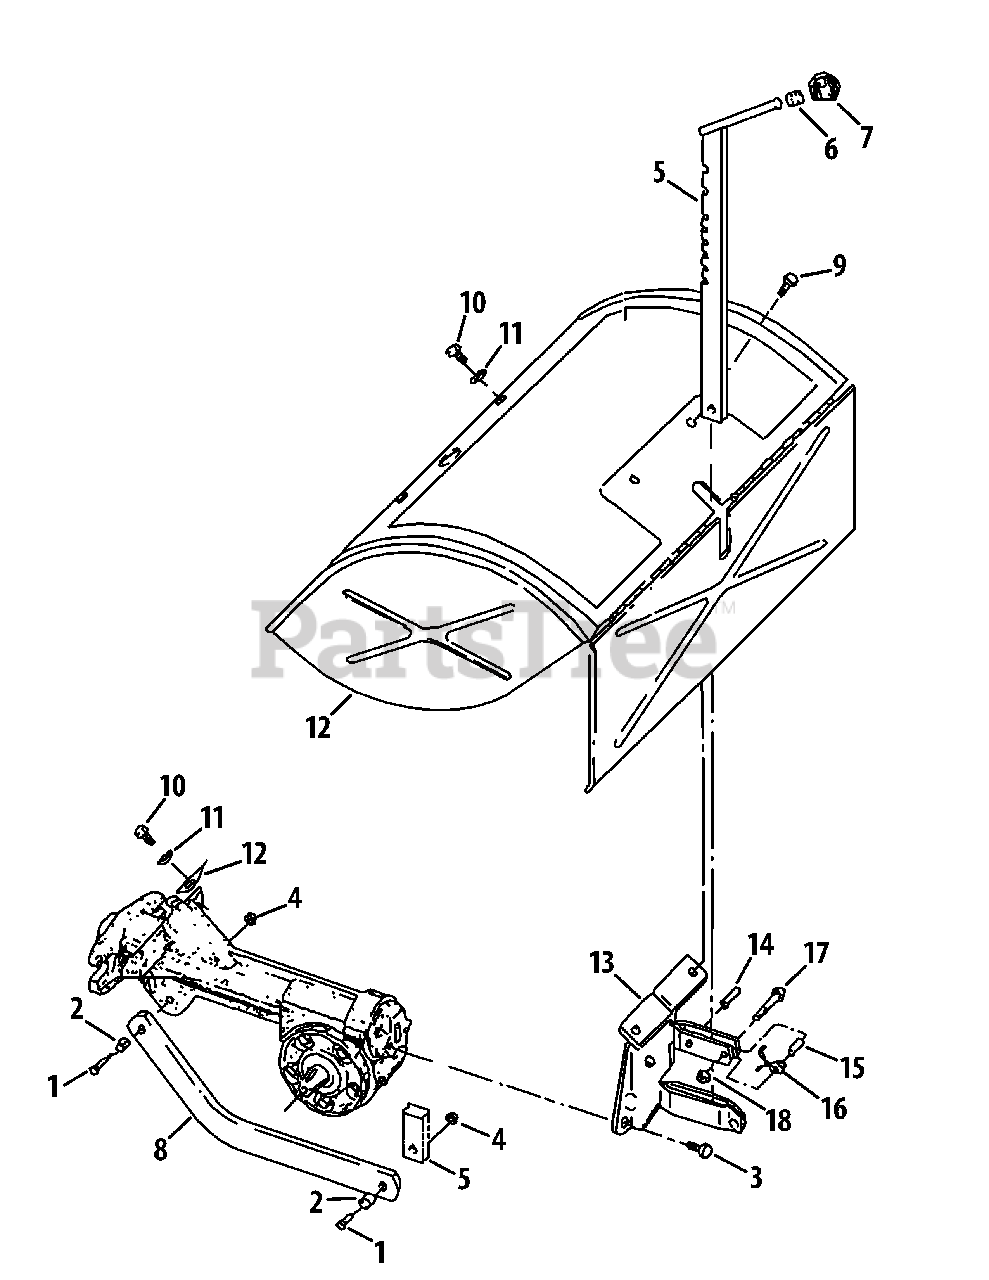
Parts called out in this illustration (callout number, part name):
1	Hex Bolt, 3/8-16 x 1-1/4
2	Bushing Spacer, .5 x .375 x .3
3	Hex Flange Bolt, 5/16-18 x .625
4	Flangelock Nut, 3/8-16
5	Depth Regulator
6	Retaining Ring
7	Depth Regulator Knob
8	Depth Regulator Bar Drag
9	Thread-forming Screw, 1/4-20 x 1/2"
10	Hex Flange Bolt, 5/16-18
11	Washer, 1.12 x .34 x .06
13	Hood Bracket
14	Roll Pin (Spirol), 1/4 x 1"
15	Split Spacer
17	Hex Bolt, 1/4-20 x 1"
18	Locknut, 1/4-20
